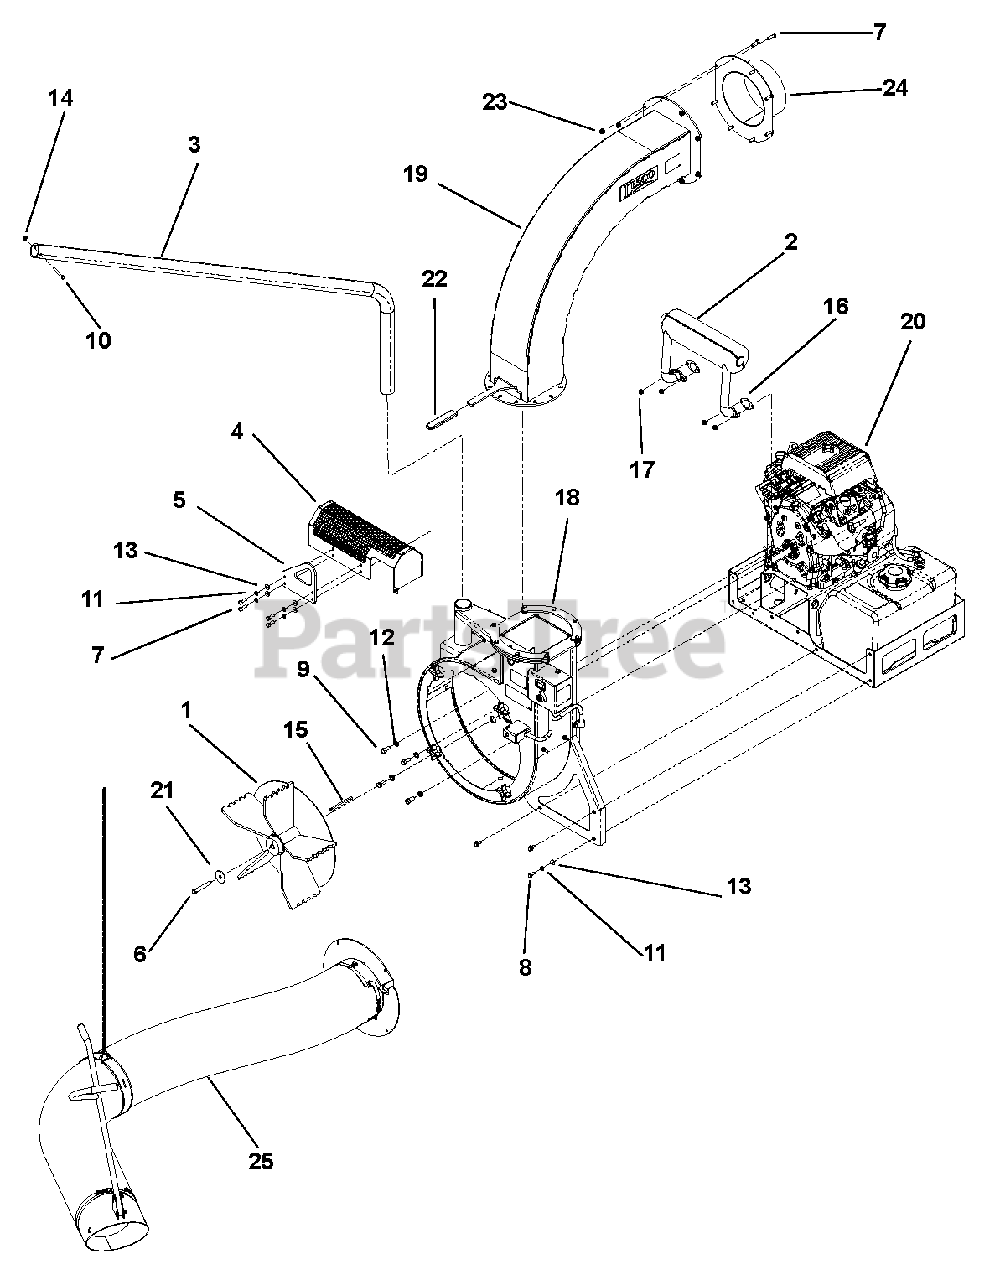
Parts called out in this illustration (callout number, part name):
1	Weldment, Impeller 5 Blade Balanced (995841)
2	Muffler, Subaru 20 HP & 22 HP
3	Support Arm
4	Weldment, Muffler Shield
5	Blower Lift Plate
6	Bolt, Hex .44-20 x 3.00 Grade YZ EP80 (995841)
7	Bolt, Hex .31-18 x 1.00 Grade 5 YWZC
8	Bolt, Hex .31-18 x .75 Grade 5 YWZC
9	Bolt, Hex .44-14 x .88 Grade 5 EP30
10	Bolt, Hex .25-20 x 2.50 Grade 5 YWZC
11	Washer, Lock .31 x .078 Reg YWZC
12	Washer, Lock .44 x .109 Reg YWZC
13	Washer, Flat .344 x .688 x .065 Stl, YWZC
14	Nut, .25-20 Nyloc Flange
15	Key, Square .250 x 4.00
16	Gasket, Exhaust Manifold EH65
17	Nut, Exhaust Manifold EH65
18	Fan Housing Assembly, 22 HP (See Fan Housing Assembly on page 8.)
19	Assy, Exhaust Tall W/Decals (Grn)
20	Engine and Base Assembly, 22 HP (See Engine & Base Assembly on page 6.)
21	Washer, Area Vac 35, 29/64 x 13/4X
22	Grip, Rubber Lever
23	Nut, .31-18 Nyloc Flange YXZC
24	Weldment, Discharge 8"
25	Vacuum Hose Assembly, 12" (See Vacuum Hose Assembly on page 10.)
